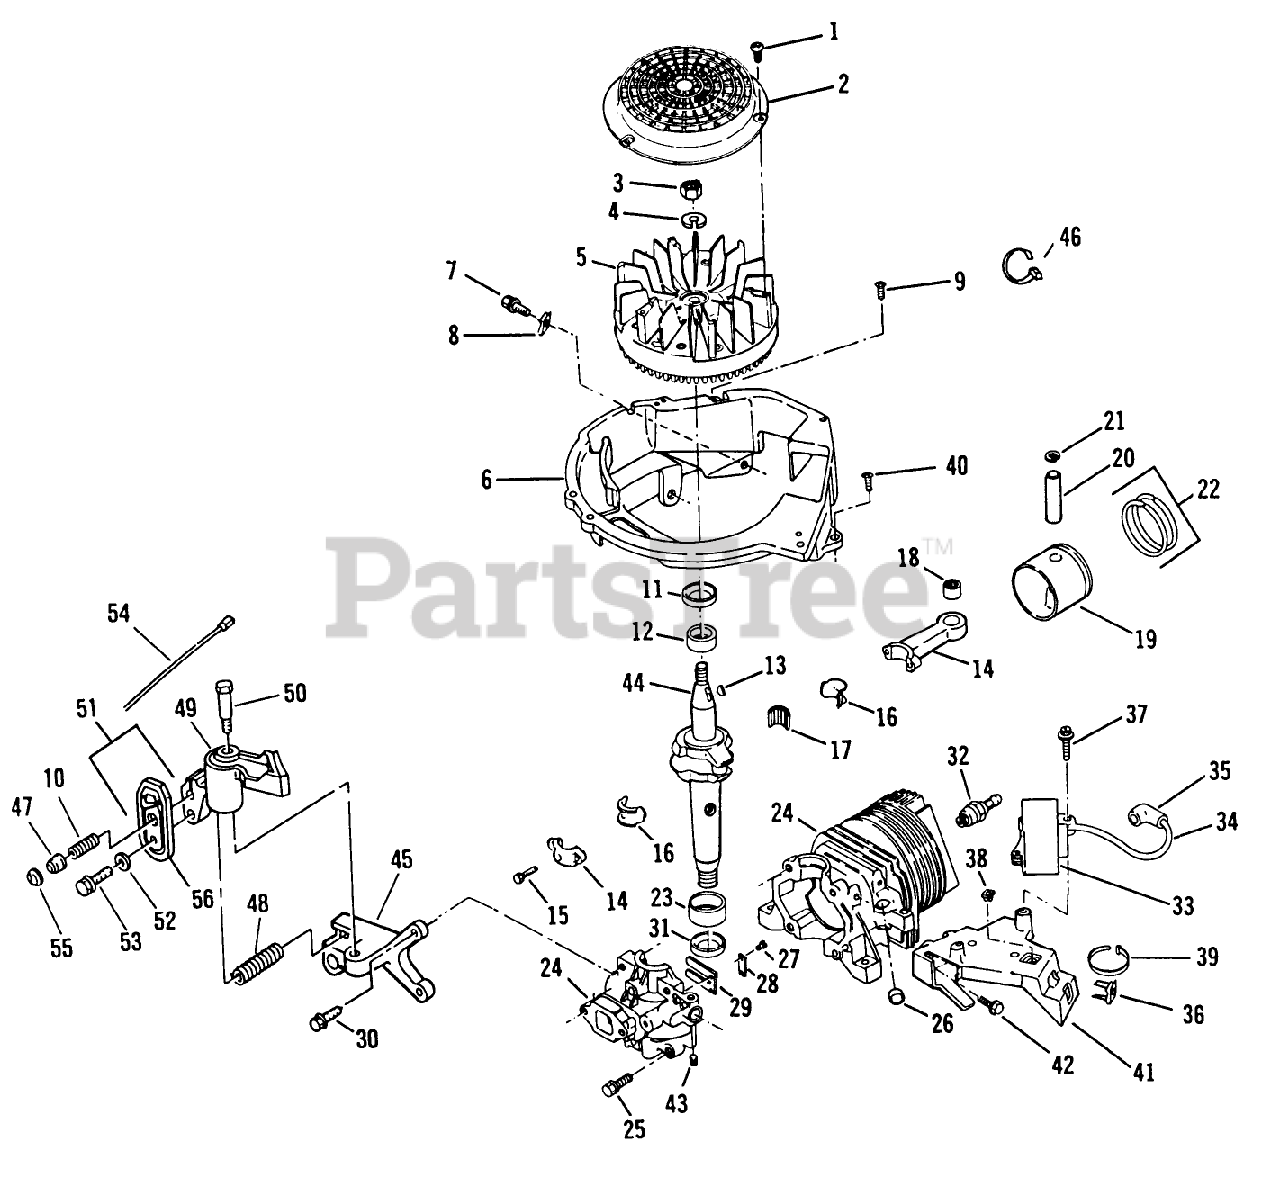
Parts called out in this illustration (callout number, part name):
1	SCREW F
3	NUT
5	FLYWHEEL ASSY F
7	SCREW-SEMS
9	SCREW F
10	SPRING
11	SEAL-OIL
12	BEARING V
13	KEY
15	SCREW-HSH
16	LINER ASM
17	BEARING-NEEDLE
18	BEARING AY F
21	RING-RETAINING
23	BEARING V
25	SCREW-H.W.HD. F
26	PLUG-CORE VF
27	SCREW-HH
28	PLATE-BACKUP, REED
30	SCREW
31	SEAL-OIL
34	HT LEAD&COVER XEV
36	NUT-CLIP
38	NUT-CLIP
40	SCREW F
45	BRACKET-BRAKE F
47	ACTUATOR-LEVER, BRAKE
48	SPRING-BRAKE
52	WASHER
54	WIRE LEAD AY F
55	RETAINER S
